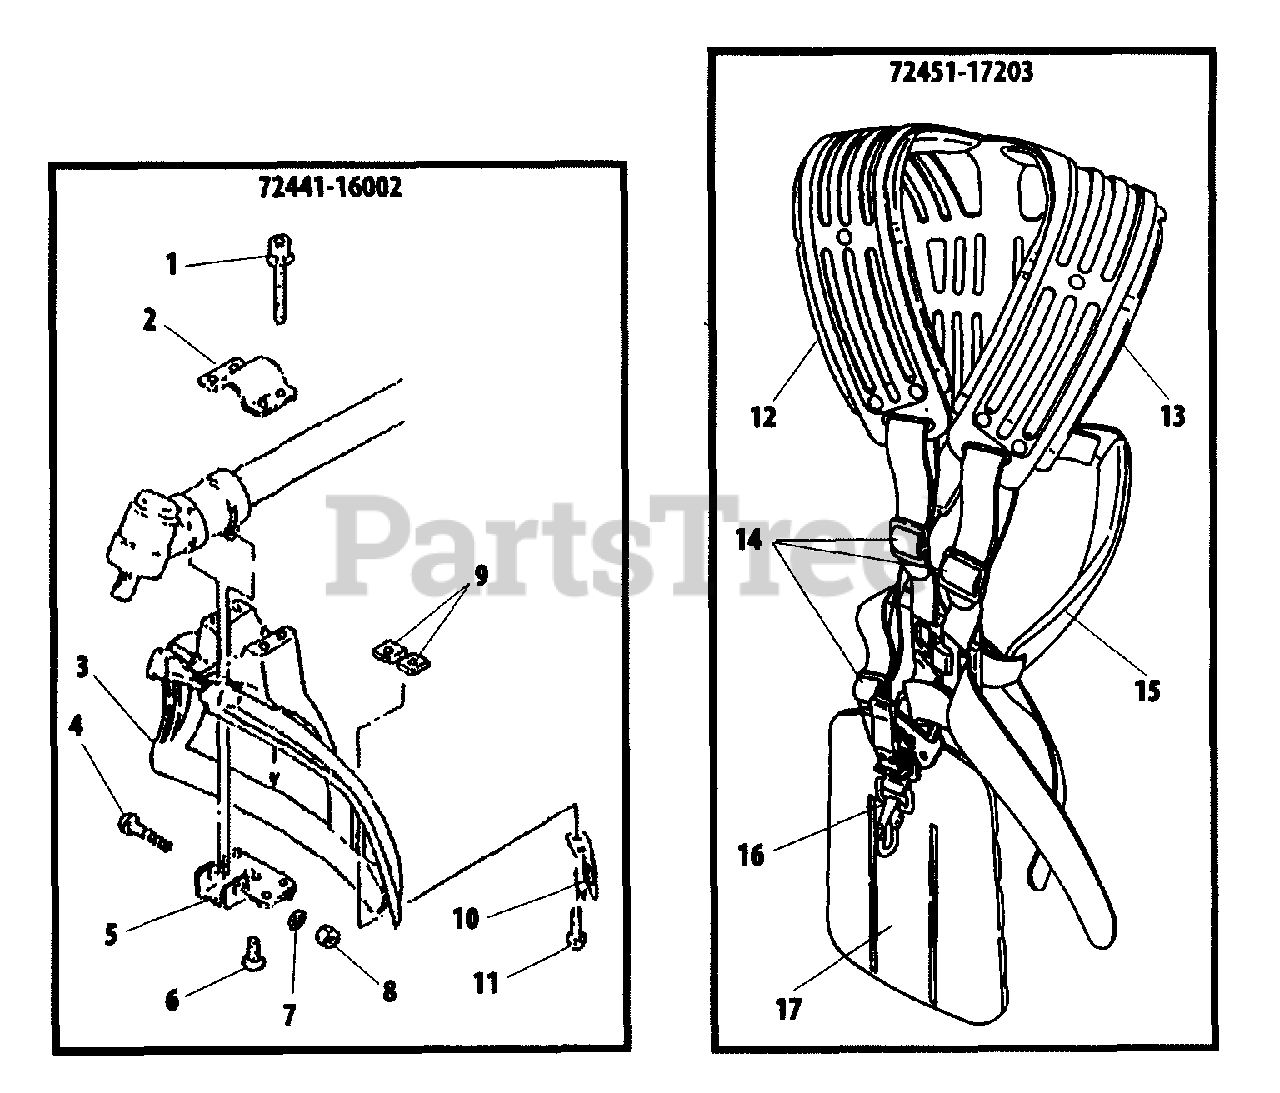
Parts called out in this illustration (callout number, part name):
1	SCREW - 5X45
2	CLAMP - UPPER
3	SHIELD, DEBRIS
4	SCREW - 6X40
5	CLAMP - LOWER
6	SCREW
7	WASHER - 6
8	NUT - 6
9	NUT - 5
10	KNIFE, TRIMMER LINE
11	SCREW - 5X16
12	PAD, SHOULDER - RIGHT
13	PAD, SHOULDER - LEFT
14	BUCKLE
15	PAD
16	HOOK
17	PAD
72441-16002	DEBRIS SHIELD KIT
72451-17203	HARNESS ASSY
